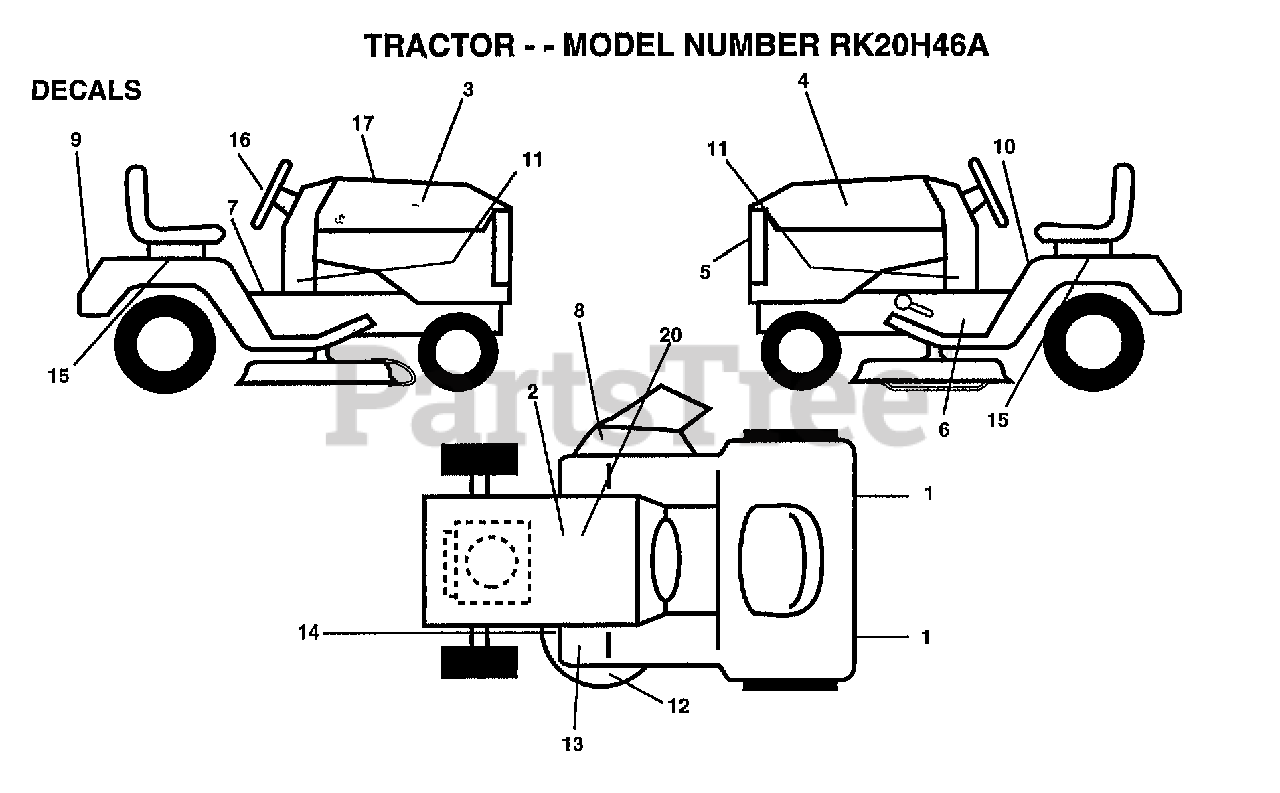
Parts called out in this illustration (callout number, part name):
1	REFLECTOR-TAIL YT
3	DECAL.HOOD.RH
4	DECAL.HOOD.LH
5	DECAL.GRILLE.LENS
6	DECAL.CHASSIS
7	DECAL SADDLE OPER
8	"DECAL, WARNING"
9	DECAL.FNDER.LOGO
10	DECAL.CAUT.ENG/FR
11	DECAL.DASH
12	DECAL.MOWER
13	DECAL T
15	DECAL.FENDER.SIDE
16	DECAL.STRNG.WHL
17	DECAL.HOOD.REP.PRTS
20	DECAL.BATRY.3-3908
